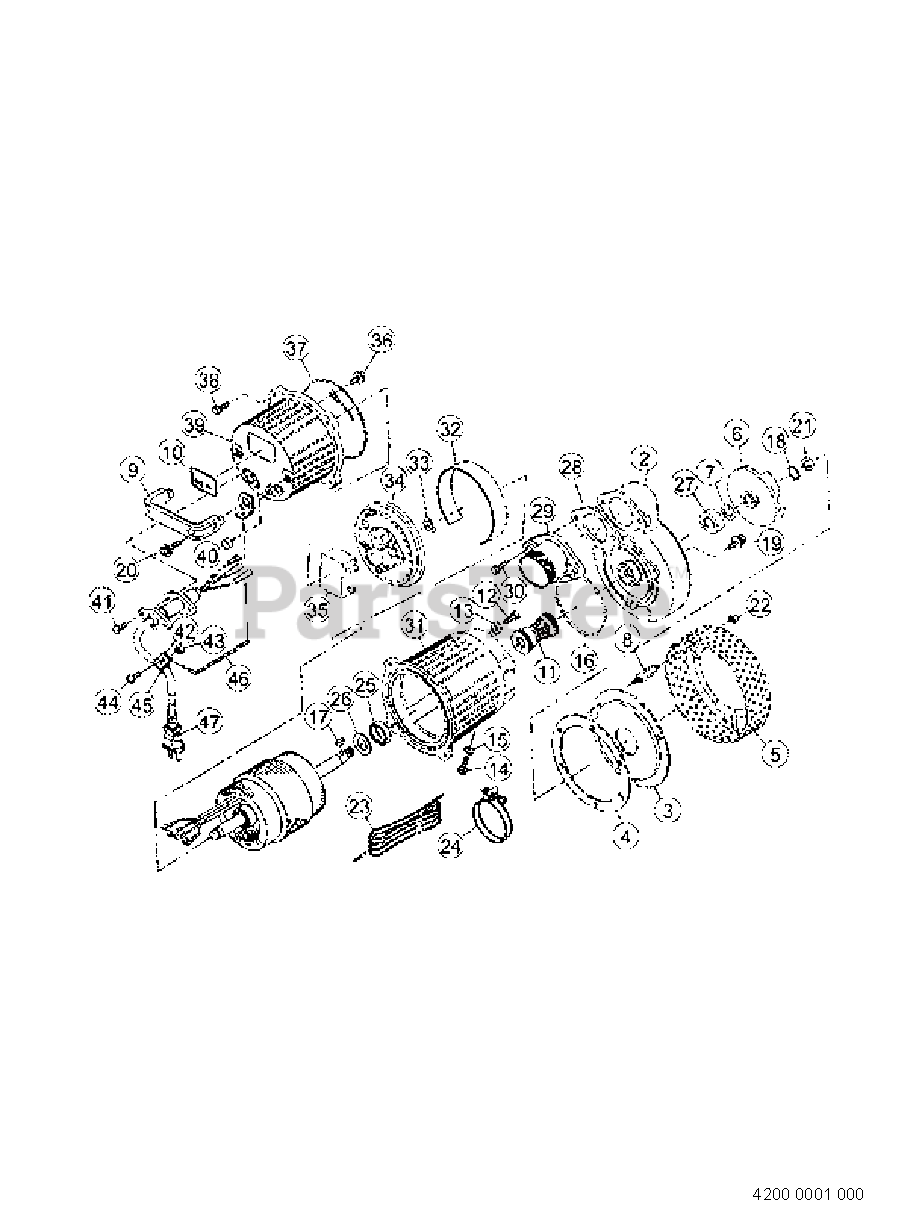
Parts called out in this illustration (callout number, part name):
2	CASING
3	SUCTION COVER
4	SUCTION GASKET
5	STRAINER
6	IMPELLER
7	ADJUSTING WASHER
8	STUD BOLT
9	HANDLE
10	LABEL
11	MECHANICAL SEAL
12	SCREW
13	SEAL RING
14	HEX BOLT
15	SEAL WASHER
18	TOOTHED WASHER
19	HEX SOCKET BOLT
20	SCREW
21	HEX NUT
22	HEX NUT
23	ROPE
24	HOSE BAND
25	THRUST GASKET
26	THRUST WASHER
27	OIL SEAL
28	DELIVERY GASKET
29	DELIVERY GASKET
30	HEX BOLT
31	FRAME
32	SUPPORTER
33	WAVE WASHER
34	BRACKET
35	CONDENSER
36	SCREW
37	HEAD GASKET
38	HEX BOLT
39	HEAD COVER
40	HEAD BUSHING
41	SCREW
42	CORD BAND
43	HEX NUT
44	SCREW
45	CORD SUPPORTER
46	CHAIN AY
